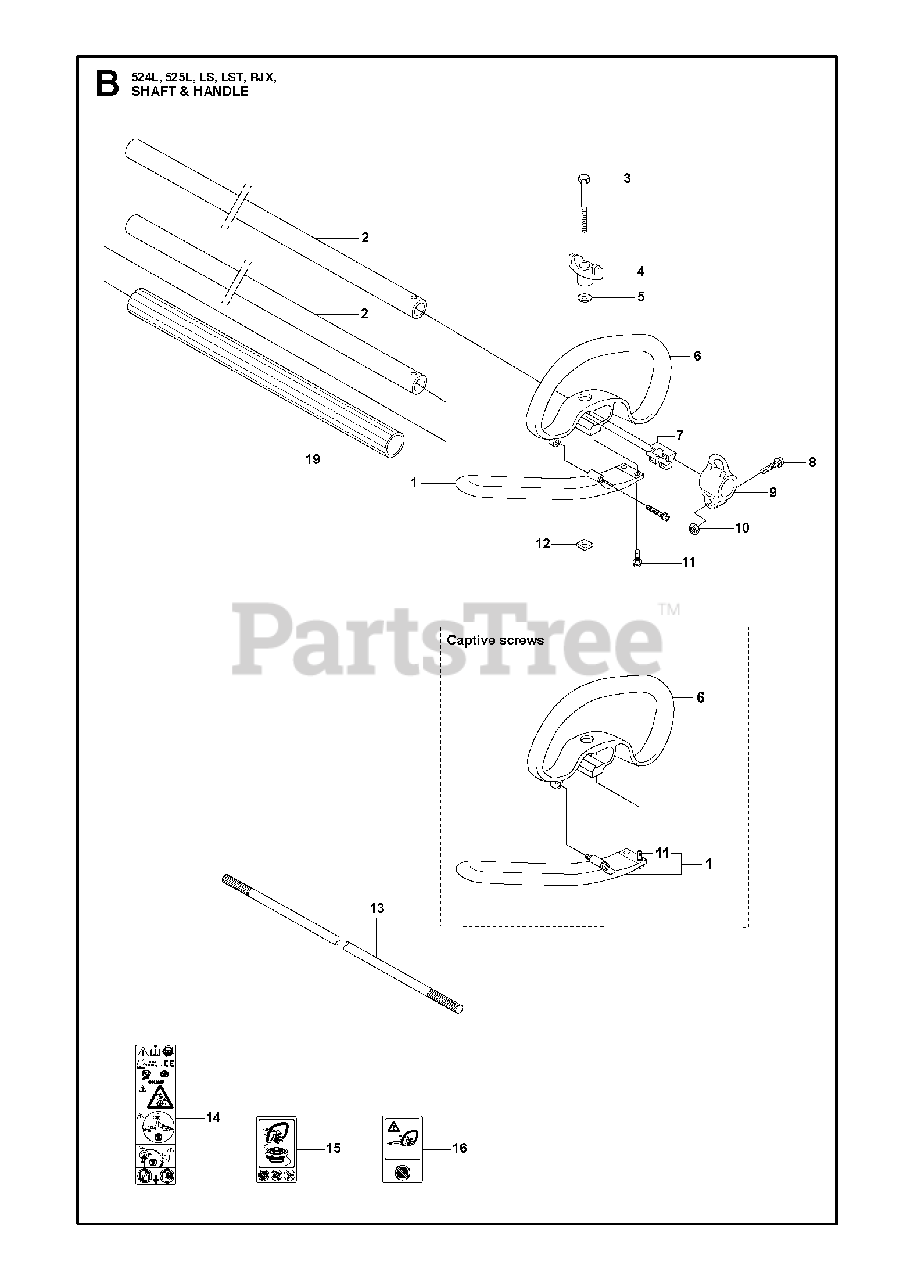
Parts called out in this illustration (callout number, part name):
1	HANDLE
2	TUBE
3	BOLT
3	SCREW M6X50
4	KNOB
5	WASHER
6	HANDLE
7	SPACER PLASTIC
8	SCREW
9	HARNESS HOLDER
10	NUT
11	SCREW IHSCFTO
13	DRIVESHAFT
14	WARNING DECAL
15	DECAL WARNING "NO BLADES"
16	DECAL
